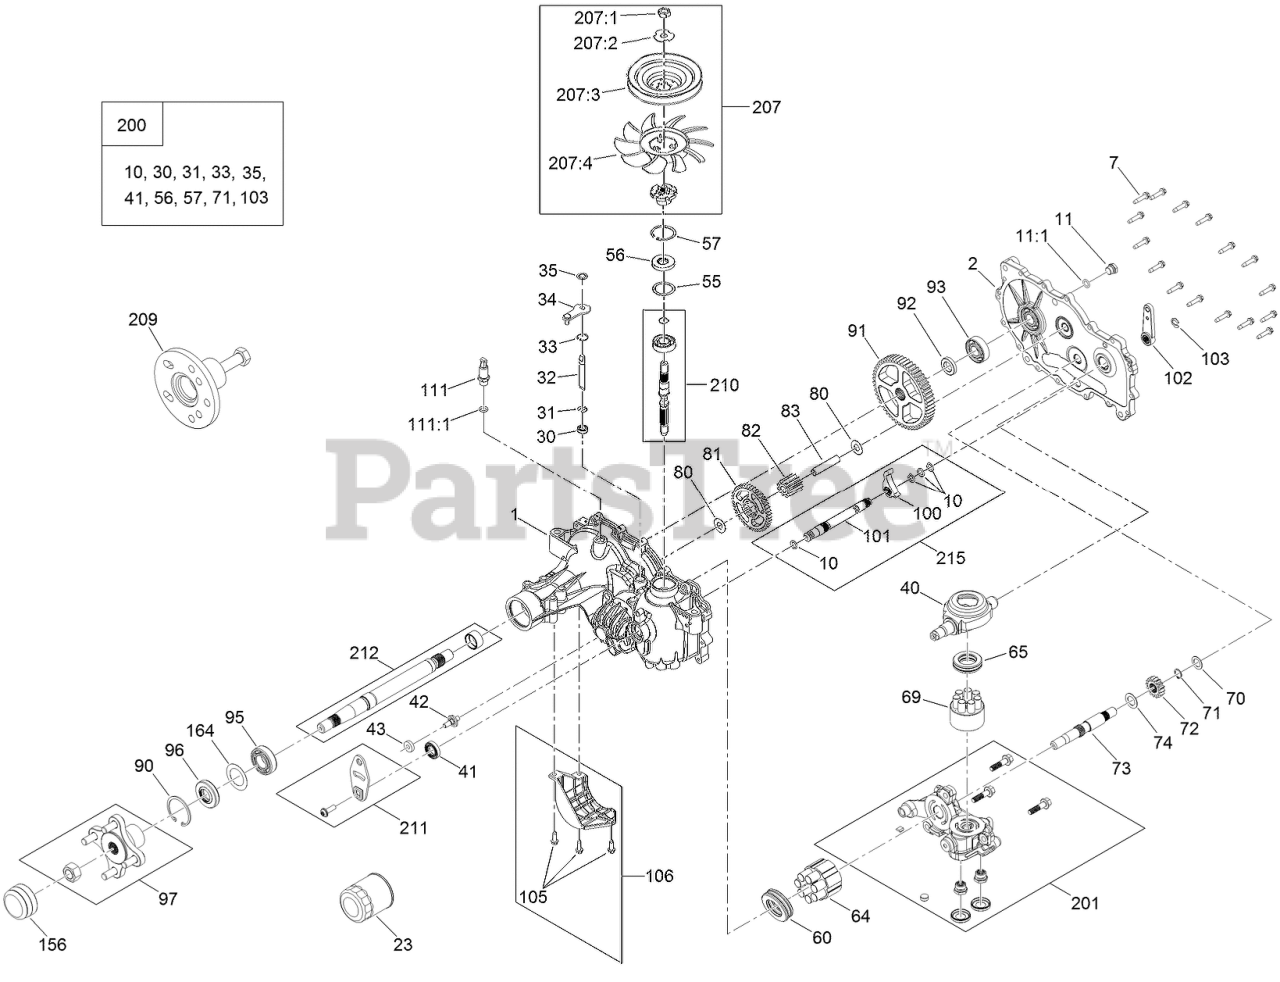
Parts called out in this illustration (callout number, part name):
1	MAIN HOUSING KIT
2	RH SIDE COVER KIT
2	LH SIDE COVER KIT
7	SCREW-HHF
10	O-RING
11:1	O-RING
23	ELEMENT-OIL FILTER, HYD
30	SEAL-LIP
31	RING-RETAINING, EXTERNAL
32	ROD-BYPASS
33	RING-RETAINING, INTERNAL
35	RING-RETAINING, EXTERNAL
40	SWASHPLATE-TRUNNION
41	SEAL-LIP
43	PUCK-FRICTION
55	SPACER
56	SEAL-LIP
57	RING-RETAINING
60	BEARING-THRUST
64	MOTOR CYLINDER BLOCK KIT
65	BEARING-THRUST
69	PUMP BLOCK ASM
70	WASHER-FLAT
71	RING-RETAINING
72	GEAR-16T
73	SHAFT-MOTOR
74	WASHER
80	WASHER
81	GEAR-43T
82	GEAR-11T
83	PIN-JACKSHAFT
90	RING-RETAINING
91	GEAR-54T
92	SPACER
93	BEARING KIT
95	INPUT BEARING KIT
97	HUB KIT
100	PAWL-BRAKE
101	SHAFT-BRAKE, INBOARD
102	HANDLE-BRAKE
103	RING-RETAINING, EXT
106	GUARD-FILTER, RH
106	GUARD-FILTER, LH
111	ADAPTER-STRAIGHT
111:1	O-RING
156	COVER-NUT, AXLE
164	SPACER
200	SEAL KIT
201	RH CENTER SECTION KIT
201	CENTER SECTION KIT
207	FAN AND PULLEY KIT
207:1	NUT-HJ
207:2	WASHER-SLOTTED
207:3	PULLEY-5.34
207:4	FAN 7.0 X 10 BLADE
210	INPUT SHAFT KIT
211	CONTROL ARM KIT
212	AXLE SHAFT KIT
215	BRAKE SHAFT KIT
